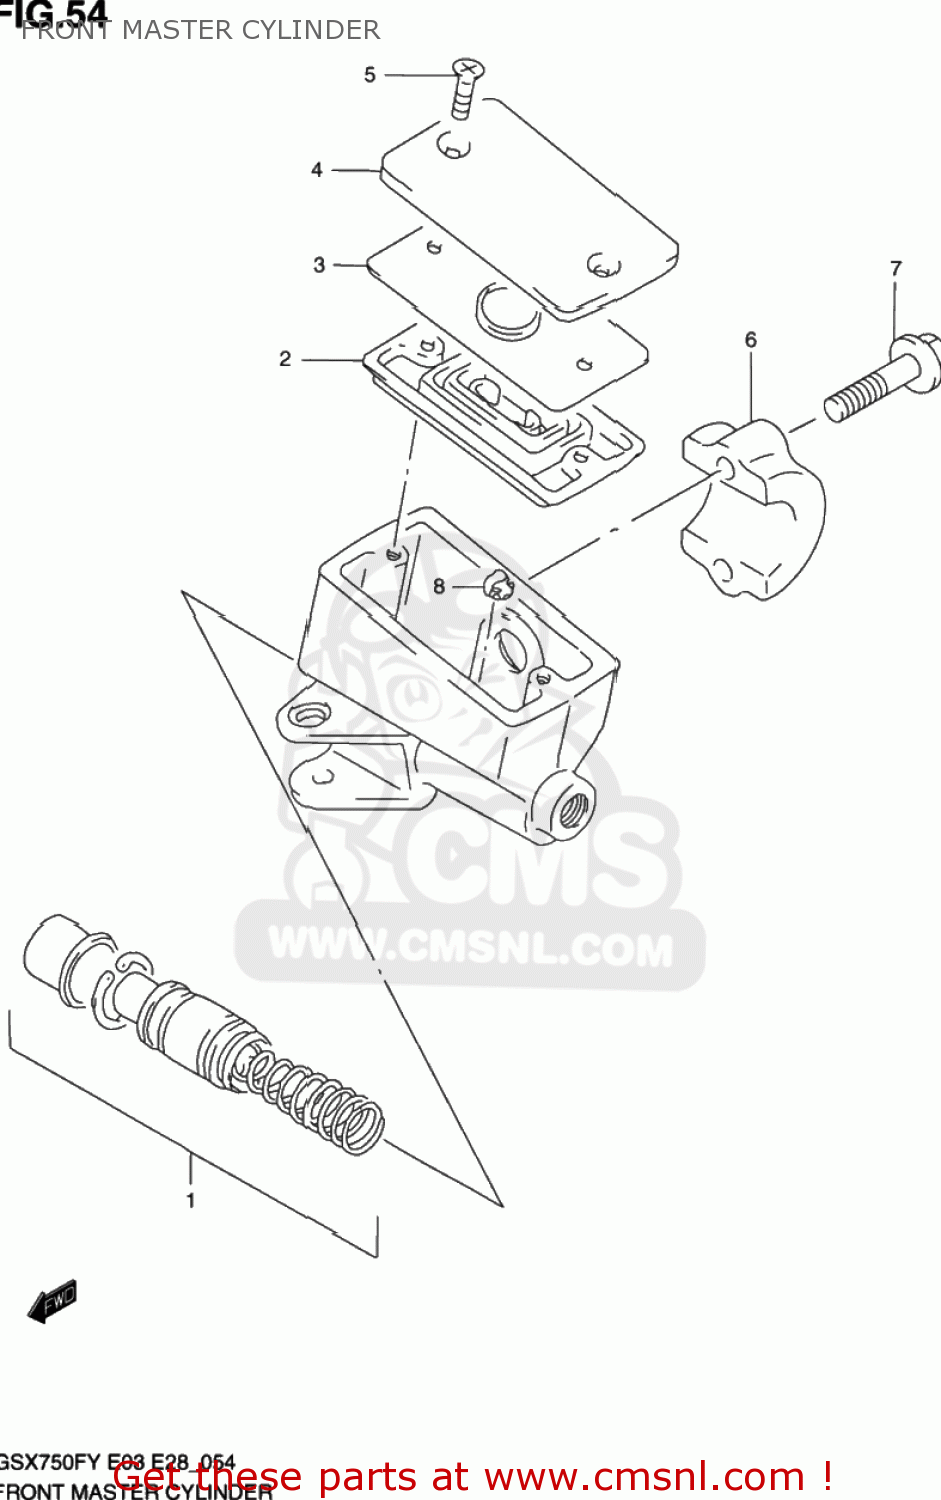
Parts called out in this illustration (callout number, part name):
1	PISTON & CUP SET
2	3
3	PLATE,DIAPHRAGM
4	CAP
5	SCREW
6	HOLDER
7	BOLT(6X25)
8	PROTECTOR
